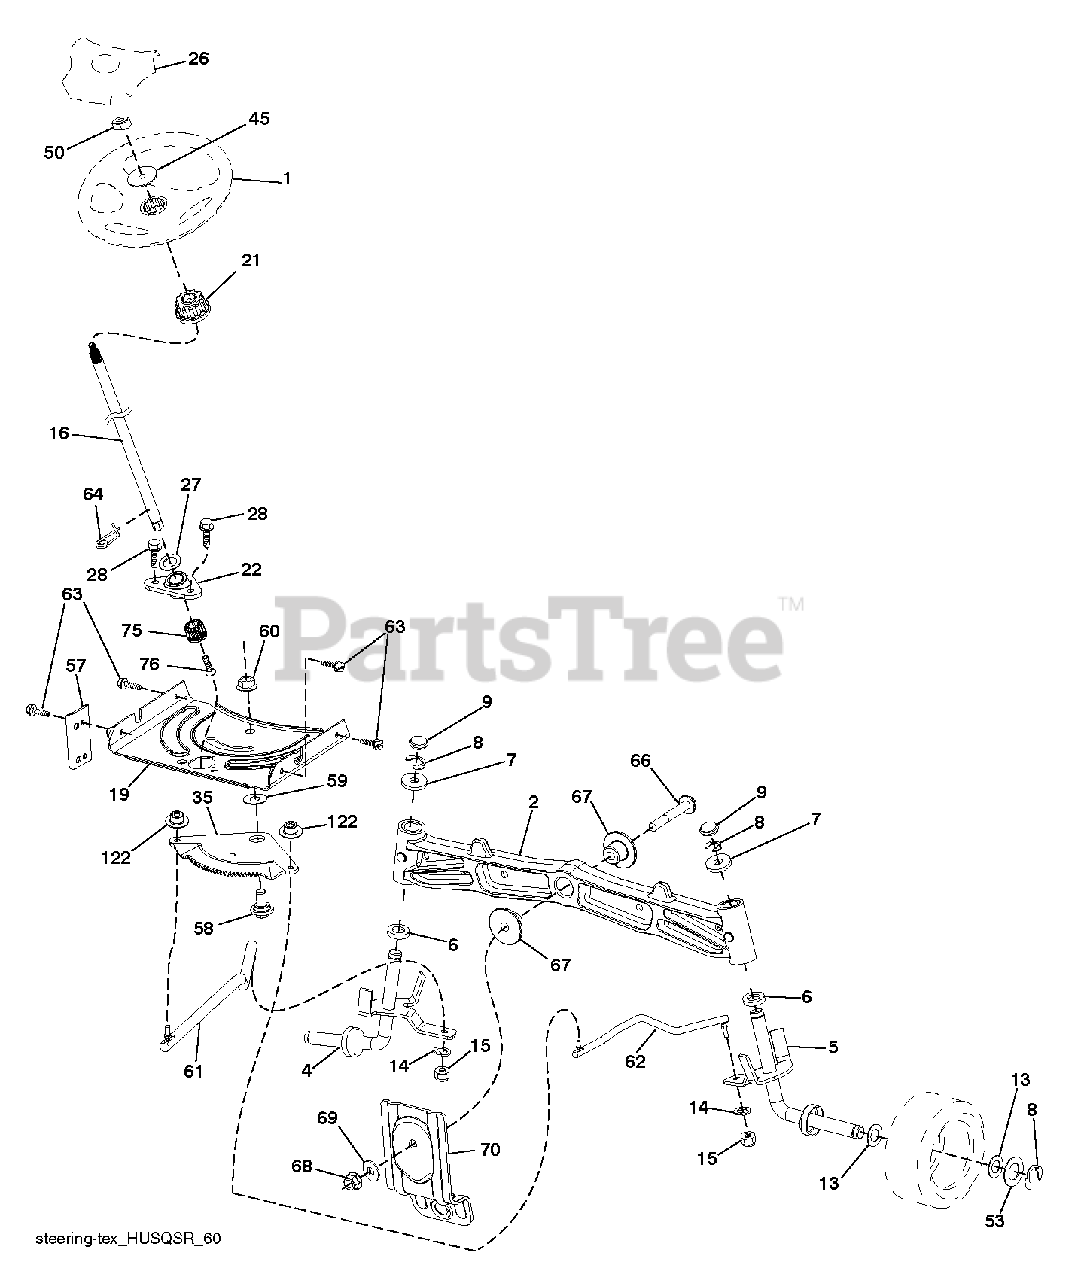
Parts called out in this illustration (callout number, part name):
1	WHEEL.STEER.HUSQ.SR.498.OVMLD
2	AXLE.CAST.IRON
4	SPINDLE.WELDED.LH.15"TEX
5	SPINDLE.WELDED.RH.15"T
6	THRUST WASHER
9	CAP.SPINDLE.BLACK
14	WASHER, LOCK 3/8
15	NUT CROWNLOCK 3/8-24
16	SHAFT.STEER.2HIGH.SPLND.PLATED
19	PLATE.STEER.DDL.NLT/NG
21	ADAPTER.WHEEL.STEER.SPLND.ALUM
22	BEARING.SHAFT.STEER.LOWER.625
26	INSERT.CAP.WHL.STRG.HUSQ.PREM
28	SCREW, 3/8-16X3/4
35	GEAR.SECTOR.PLATE.DDL.
45	WASHER 9/16"ID, 2 3/8"OD
50	NUT LOCK FLG 3/8-16 UNC
53	WASHER.HARDENED
57	BRACKET.UPSTOP.TEX
58	BOLT.SHOULDER.SECTOR.P
59	WASHER.THURST.SECTOR.S
60	NUT FLANGE LOCK 5/8-11
61	DRAGLINK.LH.ADJUSTABLE.TEX
62	DRAGLINK.RH.ADJUSTABLE.TEX
63	SCREW
64	RETAINER.CLIP.SPRING.S
66	BOLT HEX FGHD 7/16-14 X 3 SERR
67	BUSHING.PM.FRONT AXLE
68	NUT.LOCK.FLANGE.7/16
69	WASHER.1.5X.505X.118
70	BRACKET.FRT.DECK.SUSP.RR.MT431
75	PINION.ZINC PLATED
76	SCREW HEAD SOCKET LRVB
122	CAP.GEAR.SECTOR.TEX
